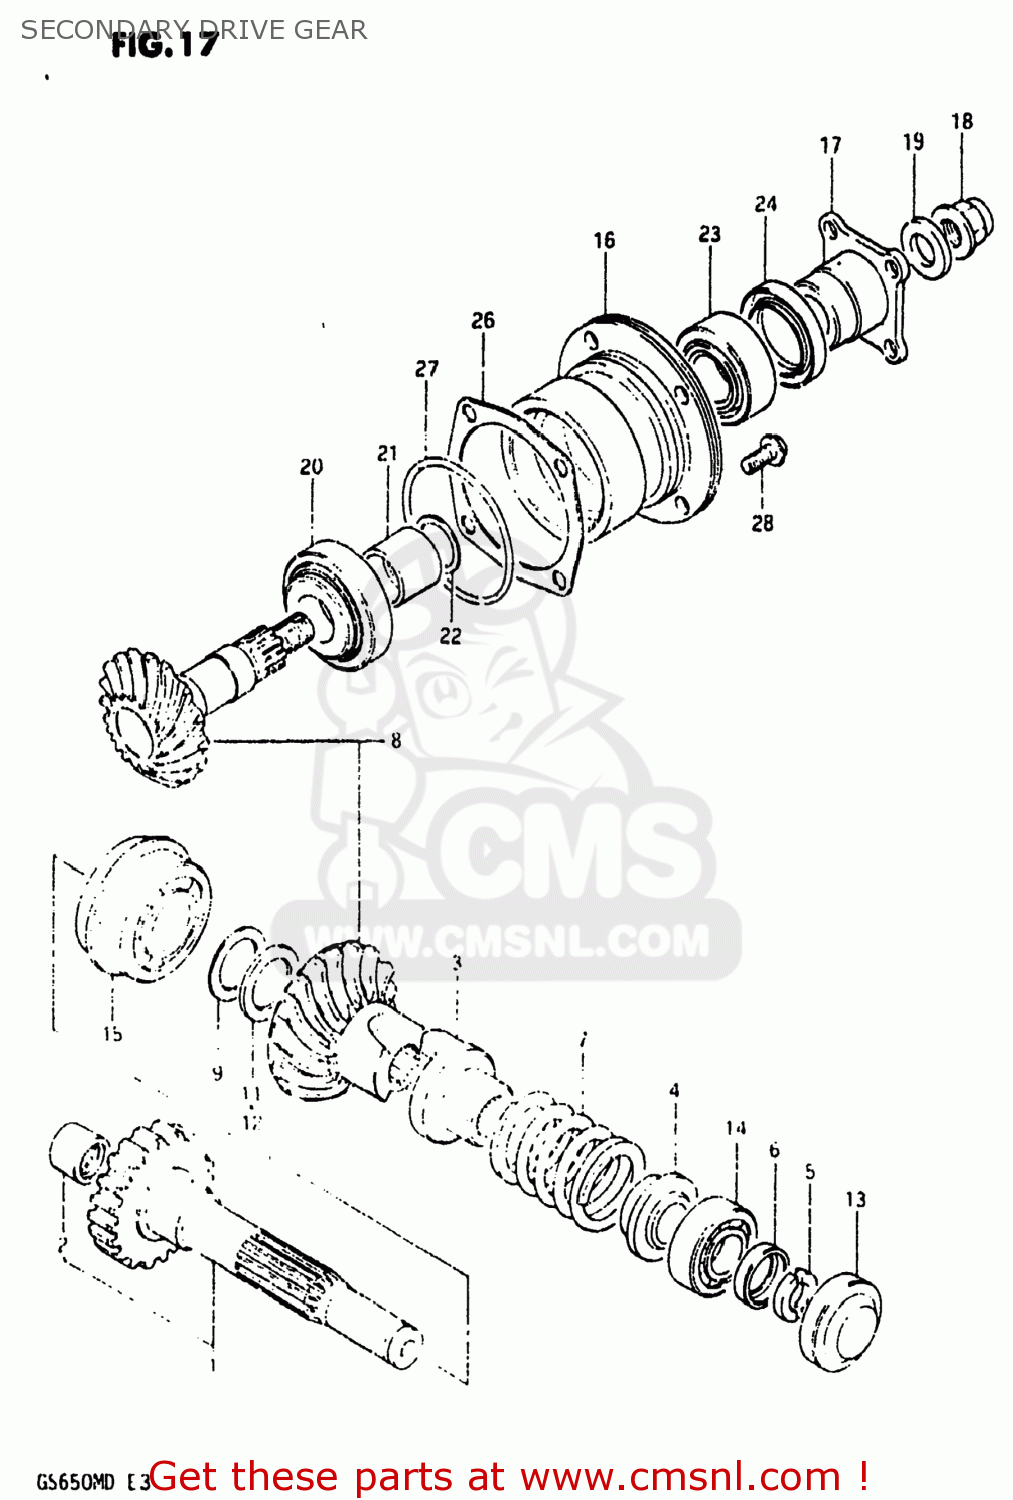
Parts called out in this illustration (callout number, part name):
1	SHAFT,OUTPUT
2	BEARING(15X23X20)
3	DOG
4	STOPPER
5	STOPPER,CAM DOG
6	HOLDER,CAM DOG STOPPER
7	SPRING
8	SECONDARY GEAR SET
9	SHIM,SECONDARY DRIVE
10	SHIM SET,SECONDARY DRIVE BEVEL
11	SHIM,SECONDARY DRIVE BEVEL
12	SHIM,SECONDARY DRIVE BEVEL
13	PLUG
14	BEARING(20X47X14)
15	BALL BEARING 30X62X24
16	HOUSING,SECONDARY DRIVE
17	FLANGE,UNIVERSAL JOINT
18	NUT
19	WASHER(14X29X4)
20	TAPER,ROLLER BEARING
21	SPACER (25.2X30X40)
22	SHIM (25X30X2
23	BEARING
24	SEAL,OIL(35X52X9)
25	SHIM SET,SECONDARY DRIVE
26	SHIM,DRIVEN GEAR HOUSING
27	O RING(D:3.1,ID:69.4)
28	BOLT
